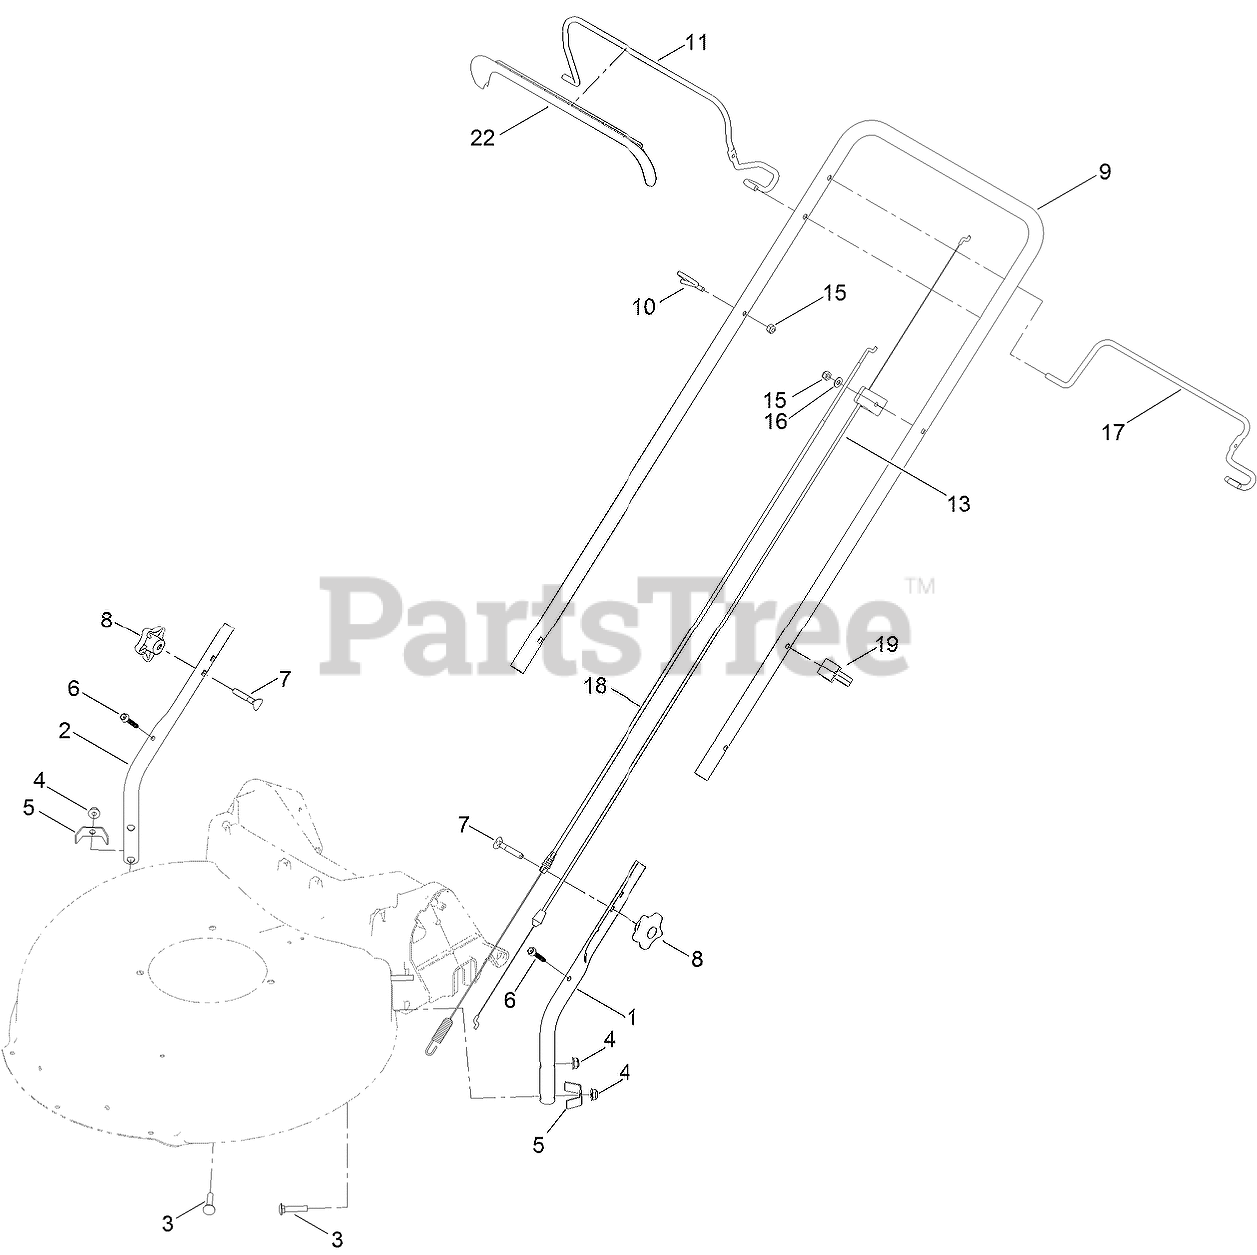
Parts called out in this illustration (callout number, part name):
1	HANDLE-LOWER, LH
2	HANDLE-LOWER, RH
3	SCREW-CARR
4	NUT-HF
5	BRACKET-CHUTE
6	SCREW-FLANGE, SERRATED
7	SCREW-HANDLE
8	KNOB-HANDLE
9	HANDLE-UPPER
10	GUIDE-ROPE
11	BAIL-BRAKE
13	CABLE-BRAKE
15	NUT-HEX
16	WASHER-FLAT
17	BAIL-TRACTION
18	CABLE-TRACTION
19	GUIDE-CABLE
22	COVER-BAIL
